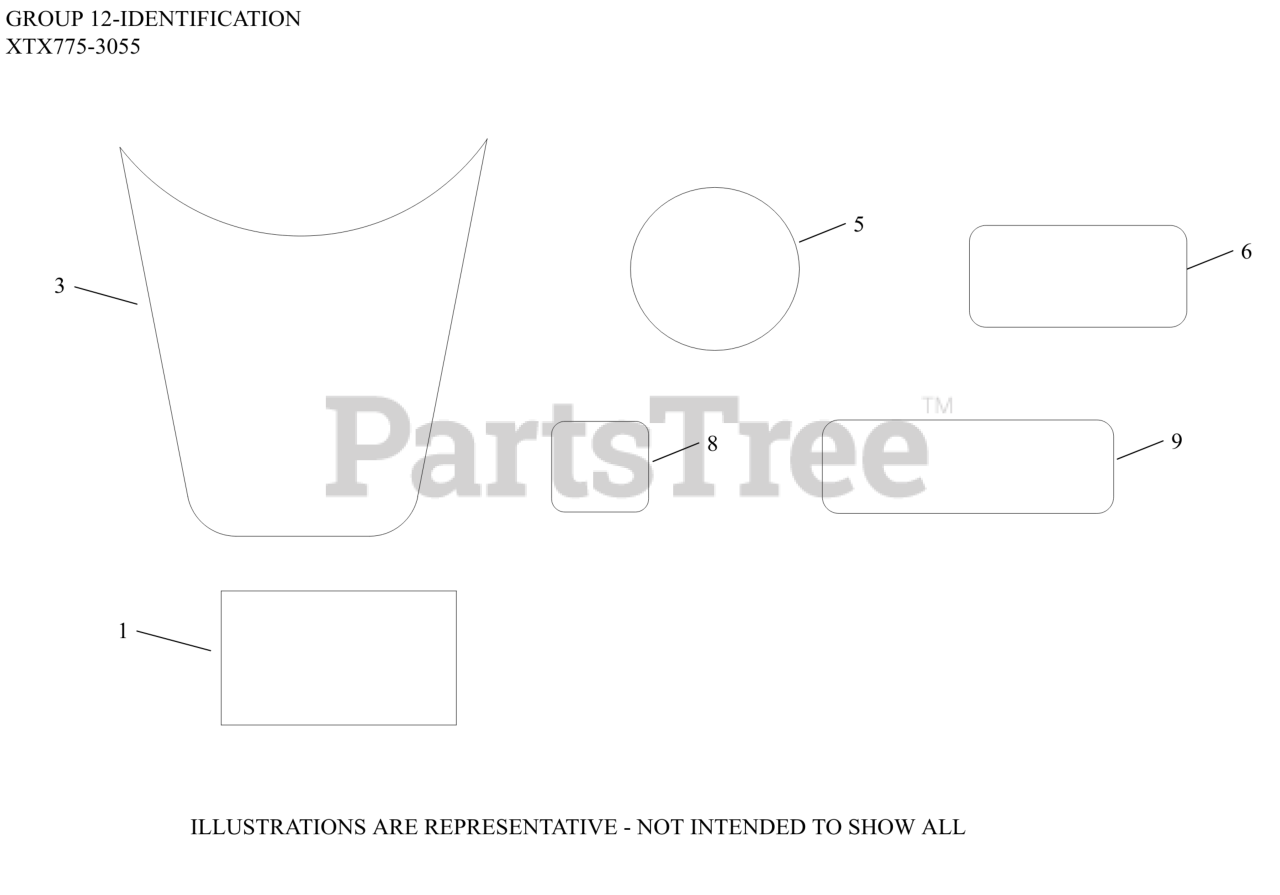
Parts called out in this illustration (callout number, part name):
1	DECAL, WARNING
3	DECAL, XTX775
5	DECAL, NAME COURAGE XT7 (TTI)
6	DECAL, HOT COURAGE XT7 (TTI)
8	DECAL, ON/OFF COURAGE XT7 (TTI)
9	DECAL, POWERED BY KOHLER
